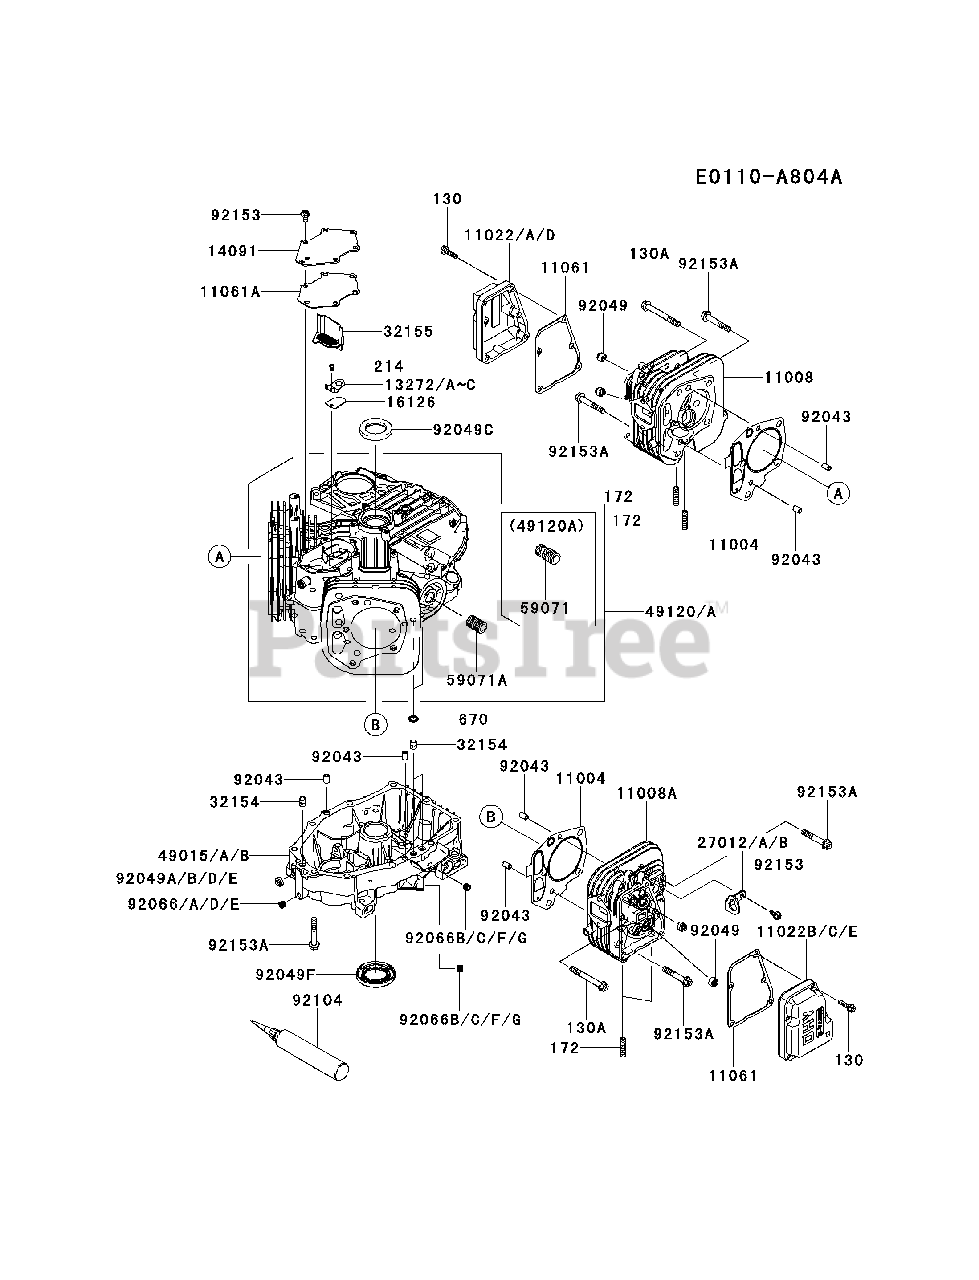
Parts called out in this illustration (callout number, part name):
130	BOLT-FLANGED,6X25
130A	BOLT-FLANGED,8X70
172	BOLT-STUD,8X18
214	SCREW-PAN+-,4X8
670	O RING,11MM
92104	GASKET-LIQUID,TB1217H
